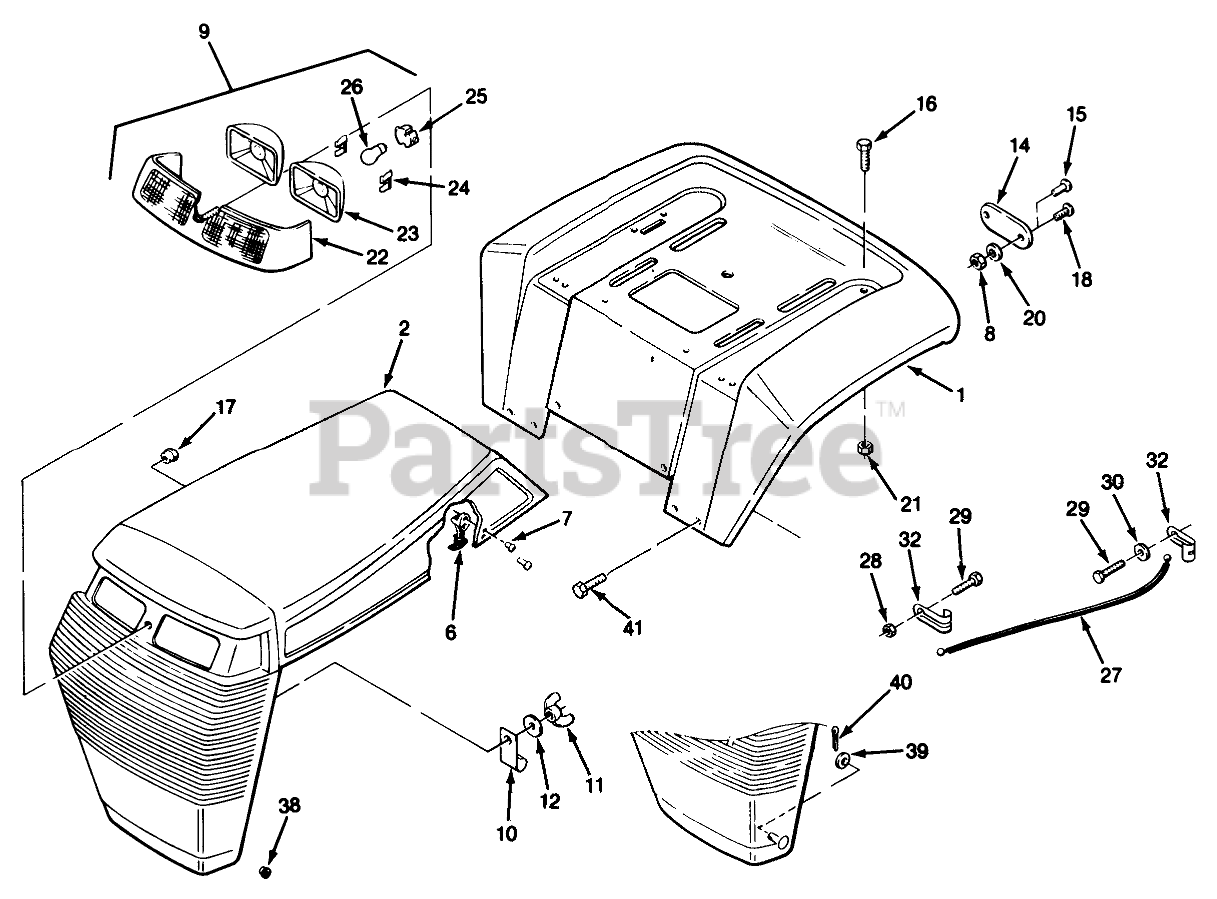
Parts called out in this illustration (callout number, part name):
1	FENDER R
2	Hood & Grill
6	HANDLE ASM
7	RIVET-POP
8	Nut
9	Headlight Bar Assembly (Incl. Ref. #22-24 & 26)
10	J-CLIP
11	WING NUT
12	WASHER
14	Reflector
15	Poprivet
16	SCREW-CARR
17	BUSHING-NYLON 1.093
18	Screw
20	Lockwasher
21	NUT-HEX
22	LIGHT-BAR BLACK
23	LIGHT POD
24	RETAINER
25	SOCKET-HEADLIGHT
26	BULB
27	CABLE-ASS'Y
28	Nut
29	Screw-Machine
30	WASHER-BACKING
32	CLEVIS
38	NYLINER BUSHING
39	WASHER-PLAIN
40	PIN-COTTER
41	BOLT-CARR
